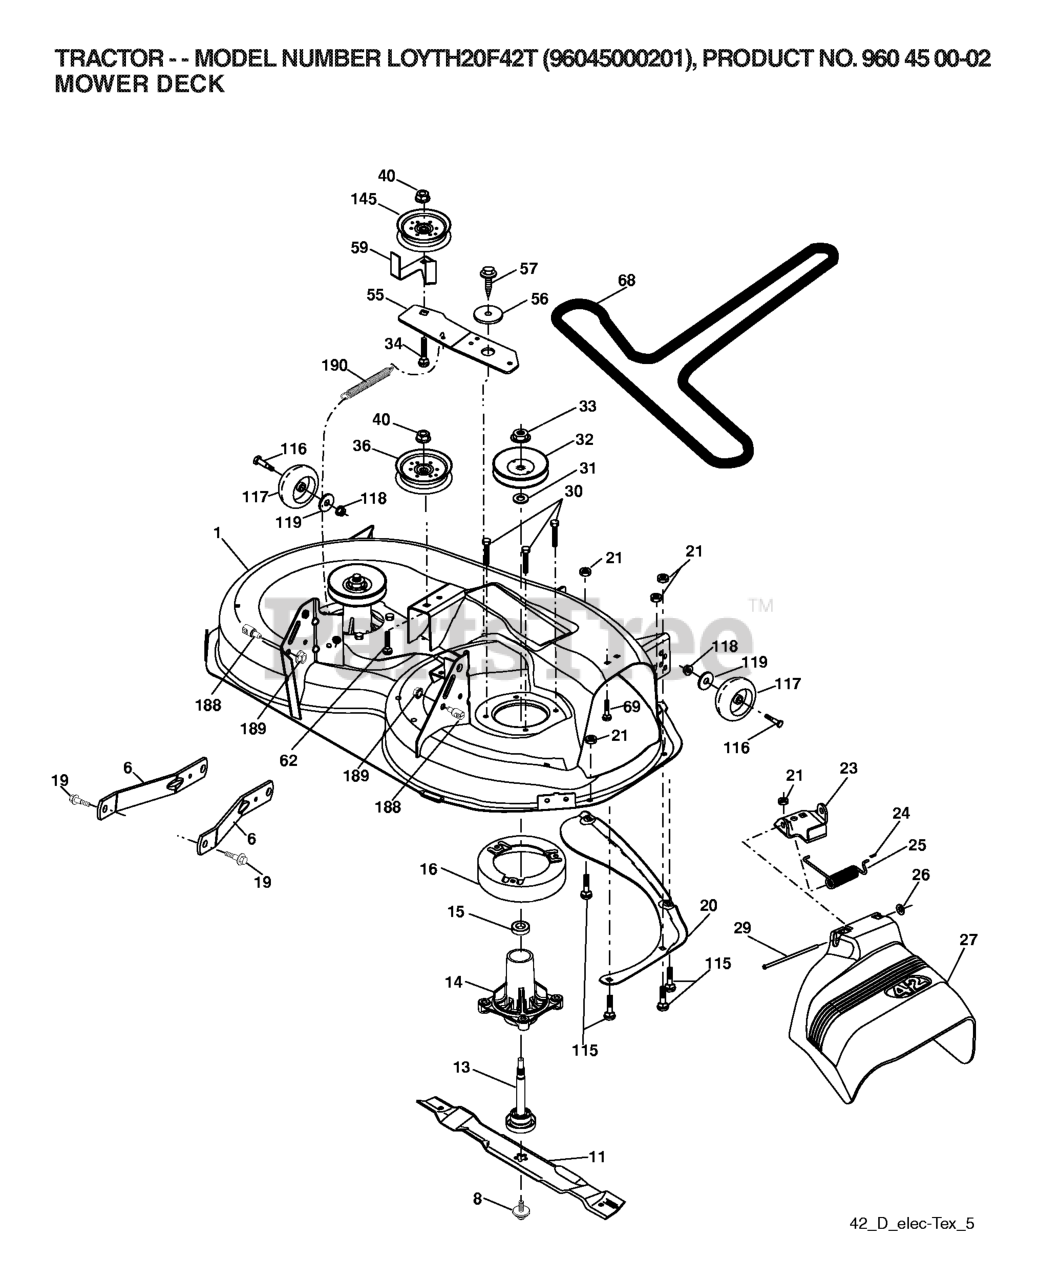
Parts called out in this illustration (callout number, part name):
1	DECK.WELDMENT.42"PAINT
6	ARM.SUSPENSION.MOWER.R
8	BOLT.WASHER.ASM.7/16-2
11	42" HI-LIFT BLADE
13	SHAFT.ASM.MDRL.N/GREASE.38
14	RP.HOUSING.MANDREL.4PT.
16	STRIPPER.MANDREL.ROUND.BLACK
19	BOLT.SHOULDER
20	BAFFLE.VORTEX
21	LOCKNUT
23	BRKT.DEFLECTOR.38"2005+
24	CAP-SLEEVE LT
25	SPRING.TORSION.DEFLECT
26	NUT PUSH M
27	SHIELD.DEFLECTOR.MOWER.42"BLAC
29	ROD.HINGE
30	SCREW, WASHER HEAD
31	WASHER.SPACER.MANDREL
32	PULLEY MANDREL
33	NUT.FLANGE.LOCK.TOP
34	BOLT.3/8-16X1.50
36	PULLEY.IDLER.2006
40	NUT LOCK FLG 3/8-16 UNC
55	IDLER.ARM
56	SPACER.RETAINER
57	SCREW 3/8-16X1
59	GUARD TUV IDLER
62	BOLT
68	BELT V SECONDARY
69	BOLT
115	BOLT.CARR.5/16-18X5/8.SHORT
116	SHOULDER BOLT
117	RP WHEEL. GUAGE RALLY
118	LOCKNUT
119	WASHER.5/16.FLAT.STE.STD.
145	PULLEY.IDLER.FLAT
188	STUD.FASTNER.W/ANTI-ROTATE
189	NUT LOCK HEX FLANGE 5/16-18
190	SPRING.MOWER.DRIVE.ELECTRIC
